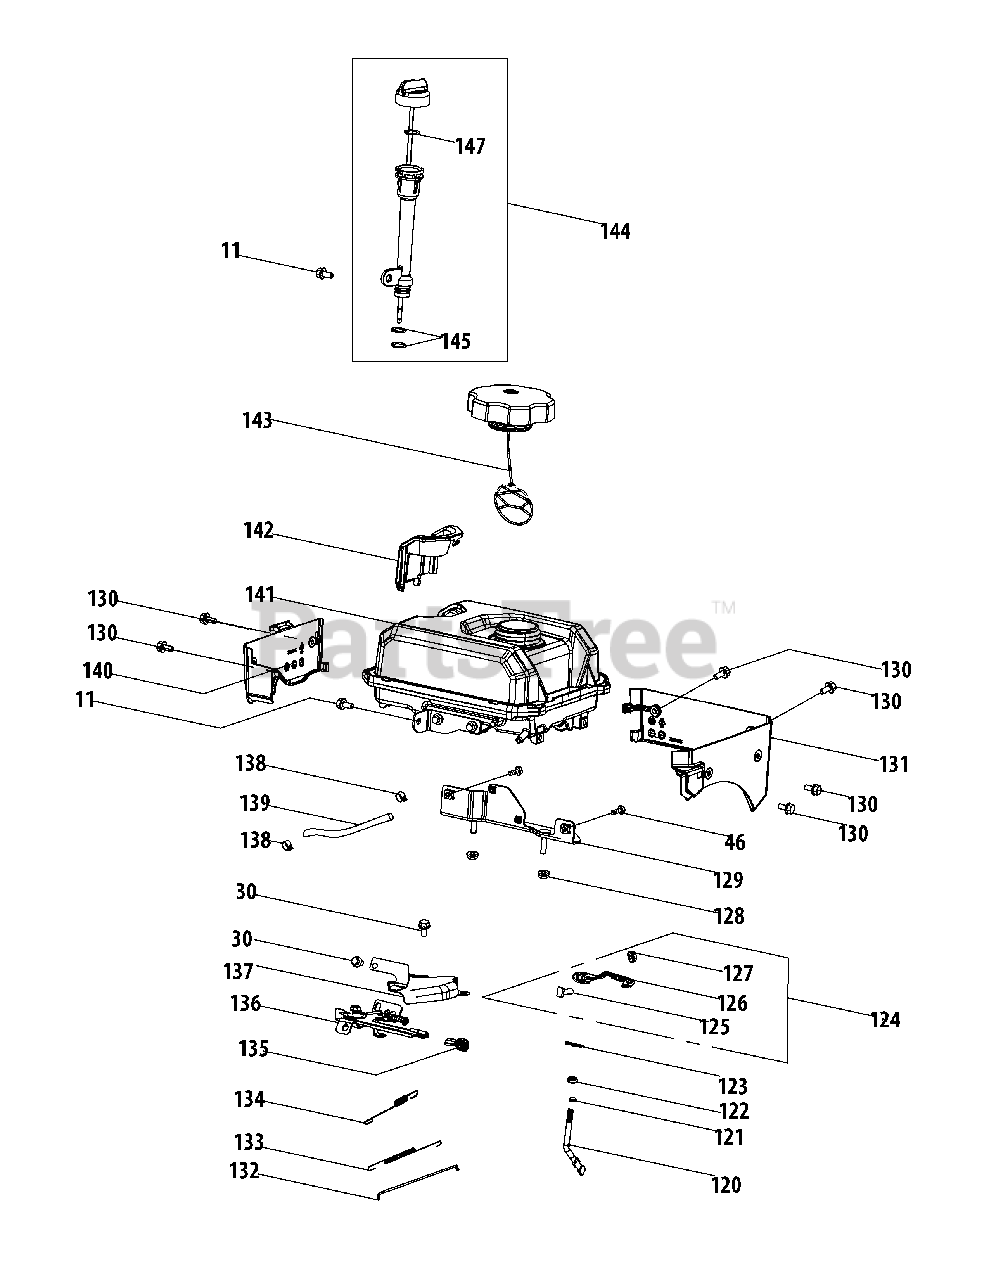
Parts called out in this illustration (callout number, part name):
11	Bolt, M6×12
30	Bolt, M6×12
46	Bolt, M6×18
120	Governor Gear Shaft
121	O-Ring, 5.2×1.9
122	Oil Seal, 6×11×4
123	Cotter Pin
124	Governor Lever
125	Bolt, M6×21
126	Governor Lever
127	Nut, M6
128	Nut, M6
129	Fuel Tank Bracket
130	Bolt, M5×14
131	Decorative Sheet, Left
132	Throttle Linkage
133	Idle Spring
134	Governor Spring
135	Throttle Lever Knob
136	Governor Gear Bracket Assembly
137	Governor Shield
138	Clamp
139	Fuel Hose, 6.3×12.5×162
140	Decorative Sheet, Right
141	Fuel Tank
142	Decorative Cover
143	Fuel Cap
144	Dipstick
145	O-Ring, 15.2×1.5
146	Dipstick
147	O-Ring, 21×2.77
